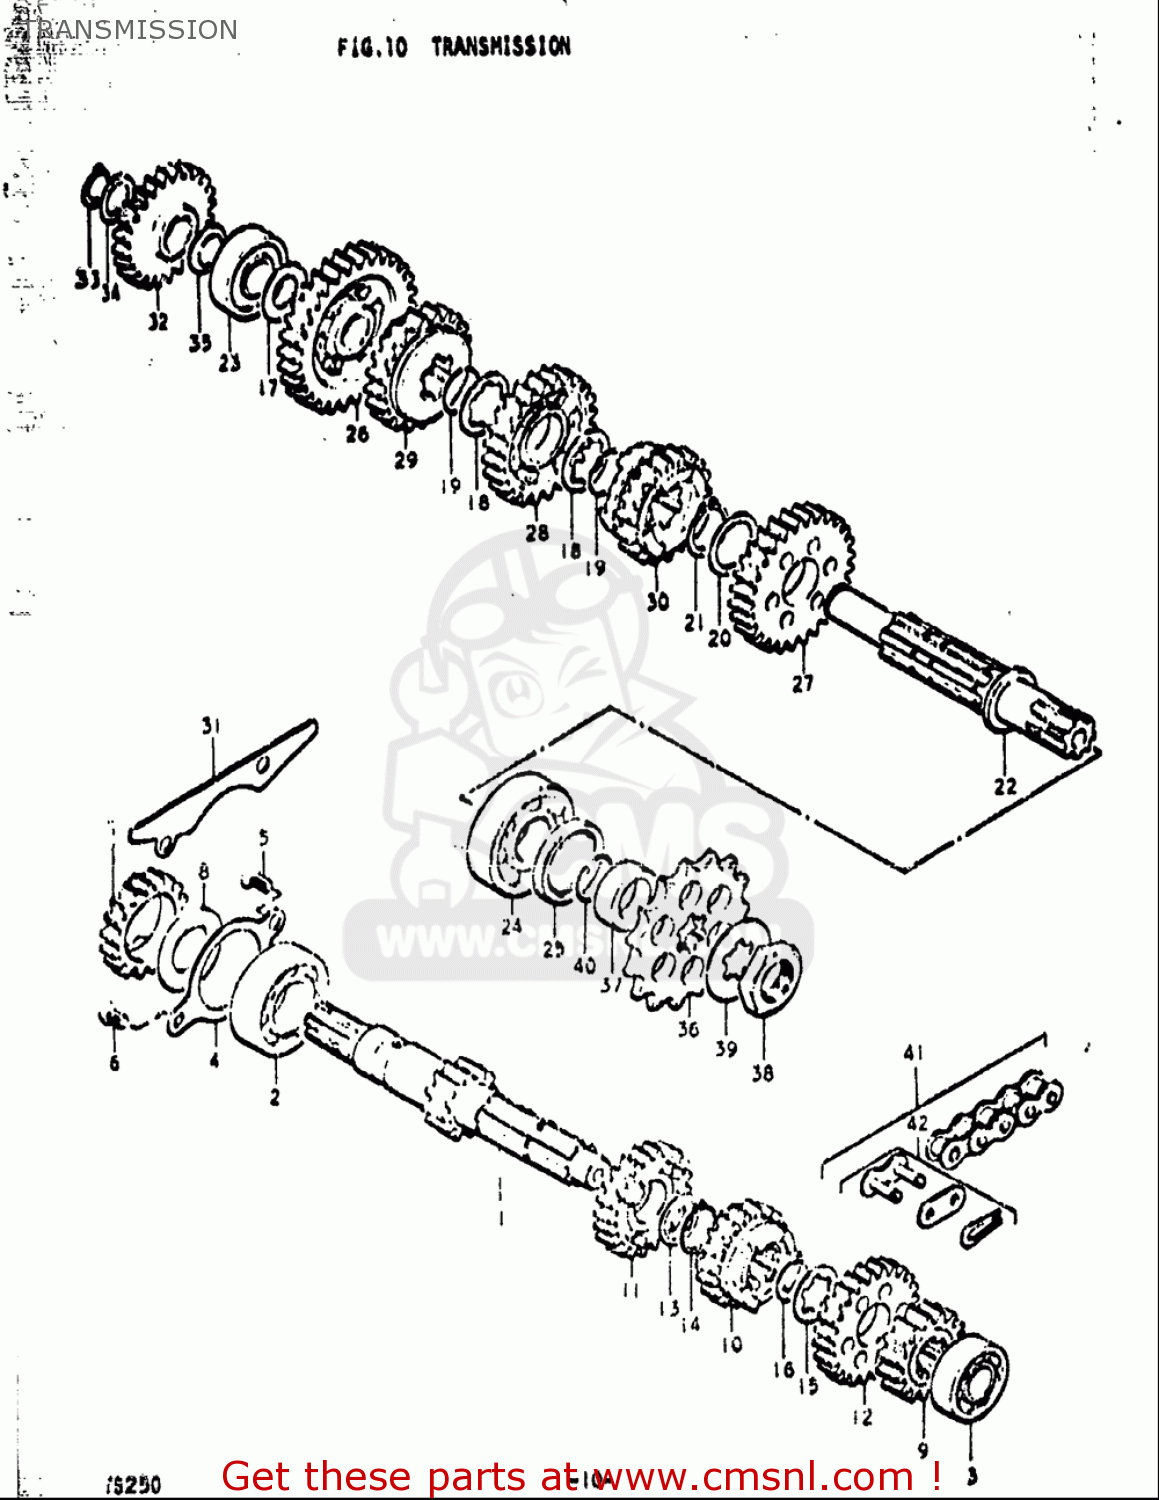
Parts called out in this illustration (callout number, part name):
2	BEARING
3	BEARING(17X40X12)
4	PLATE,COUNTERSHAFT BEARING
5	SCREW
6	SCREW
8	WASHER(25X41X3)
12	GEAR,FIFTH DRIVE
13	SHIM(22X28X1)
14	CIRCLIP
15	WASHER,LOCK
16	CIRCLIP
17	WASHER
18	WASHER
19	RING,SNAP
20	WASHER
21	RING,SNAP
23	BEARING
24	BEARING(22X56X16)
25	SEAL,OIL(32X42X6)
26	GEAR,FIRST DRIVEN
30	GEAR,5TH DRIVEN
32	GEAR,KICK STARTER IDLE
33	CIRCLIP
34	WASHER
35	WASHER
36	SPROCKET,ENGINE
37	SPACER(22X32X11.5)
38	NUT
39	WASHER,LOCK
40	O RING(D:1.7,ID:22)
41	CHAIN,DRIVE #525TR-10
42	JOINT ASSEMBLY,CHAIN
